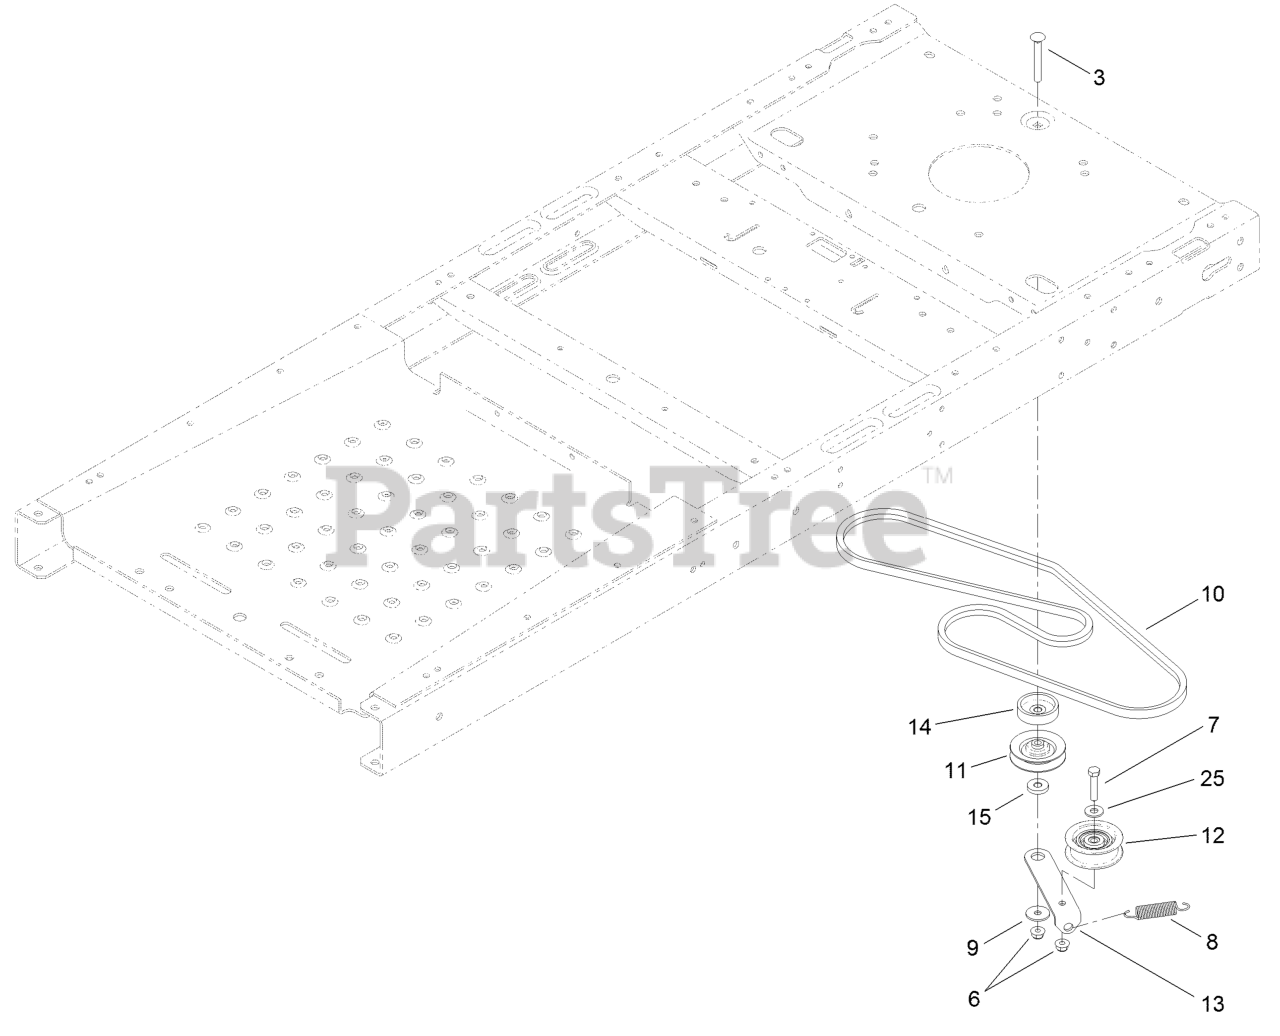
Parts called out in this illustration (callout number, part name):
1	RH HYDRO TRANSAXLE ASM
2	LH HYDRO TRANSAXLE ASM
4	SCREW-HH
5	SCREW-HH
6	NUT-HF, NI
16	4 PLY WHEEL AND TIRE ASM
16:1	TIRE-4 PLY
16:3	Stem-Valve
17	NUT-LUG
18	MOUNT-HYDRO
19	ROD-BYPASS, LH
20	SCREW-HH
21	PLATE-CROSS, HYDRO
22	SCREW-HHF
24	ROD-BYPASS, RH
26	NUT-LOCK, NI
27	WASHER-FLAT
28	SCREW-HH
29	WASHER-FLAT
30	WASHER-PLAIN
